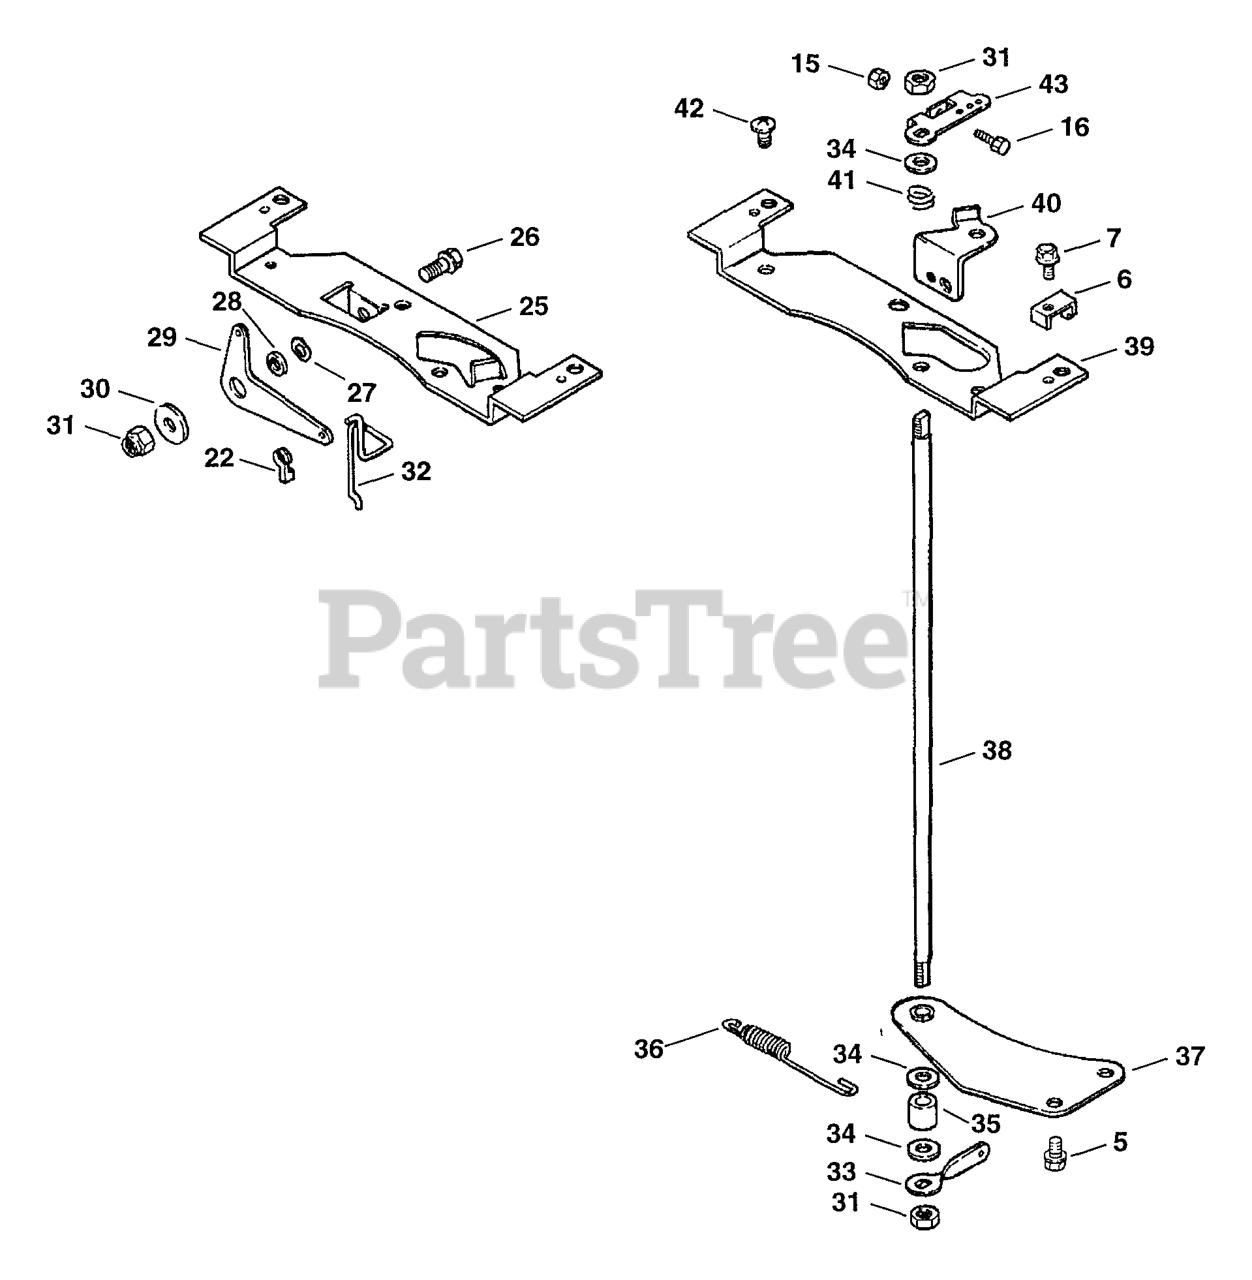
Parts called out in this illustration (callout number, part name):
5	Screw, Hex. Flange M6x1.0x16
6	Clamp, Cable
7	Screw, Hex. Flange M5x0.8x16
15	Nut, Hex. Flange M4x0.7
16	Screw, Hex. Cap M4x0.7x30
22	Bushing, Linkage - Black
31	Nut, Hex. M6x1.0
33	Lever, Throttle Control
34	Washer, Plain 1/4"
36	Spring, Governor
37	Bracket, Throttle Shaft
38	Shaft, Throttle
39	Bracket, Control
40	Bracket, Cable Support
41	Spring, Throttle Shaft
42	Screw, Phillips Hd. 11-16x3/4"
43	Lever, Throttle Control
